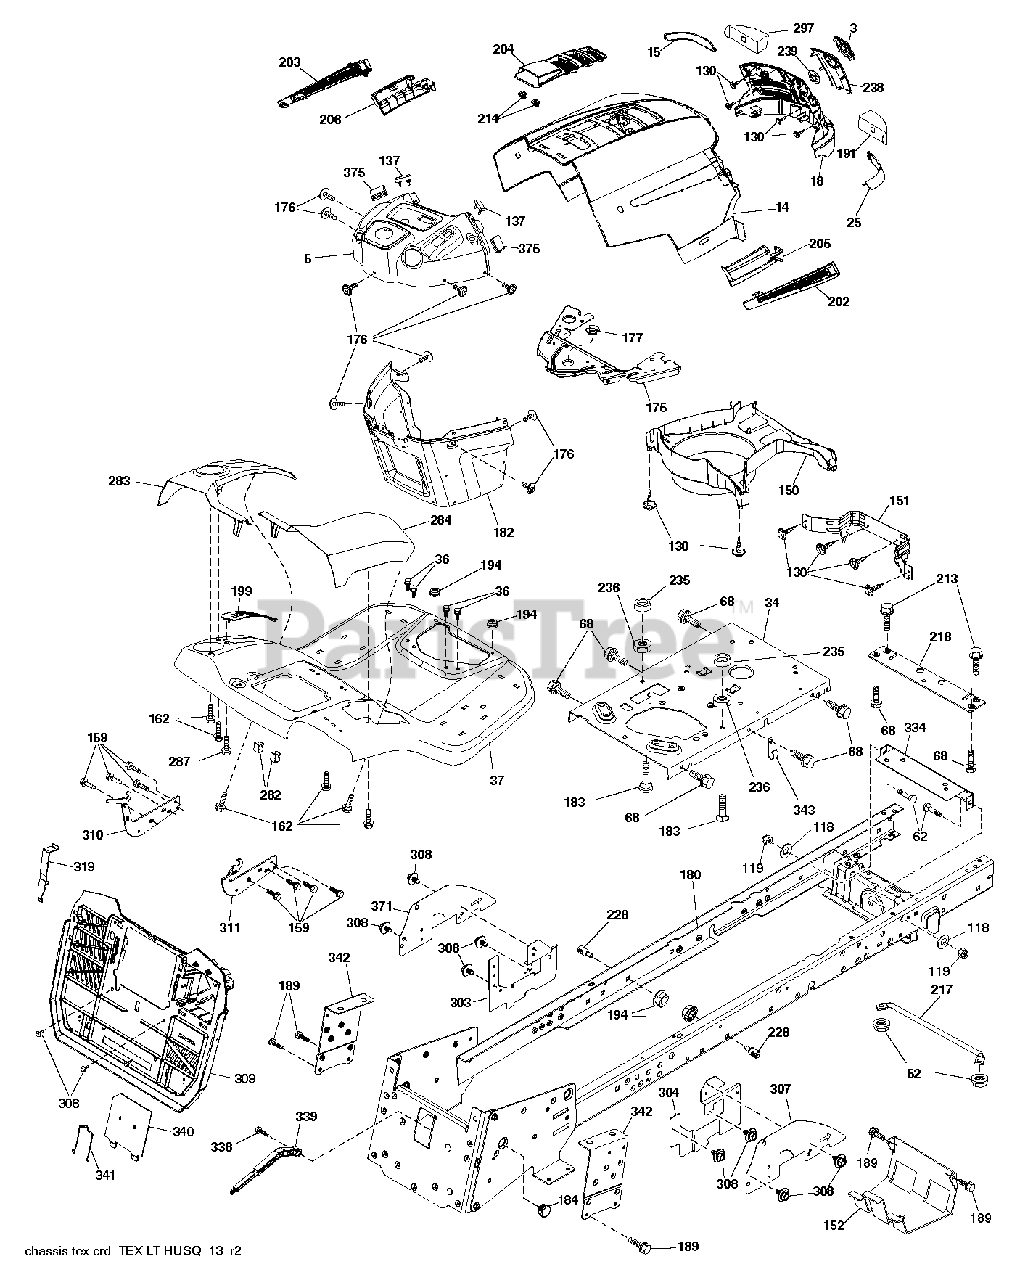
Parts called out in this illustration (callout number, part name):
3	LOGO.HUSQ.GT.LT.CROWN.H
5	DASH.UPPER.HUSQ.LT.MAN.NO-CHK
14	HOOD.HUSQVARNA.LT.ORANGE
15	LENS.HUSQVARNA LT.RH
18	GRILLE.SVC.HUSQVARNA.GREY
25	LENS.HUSQVARNA LT.RH
34	PLATE.ENGINE.10GA.CRD.GENII
36	SCREW 5/16"
37	FENDER.TEX.SRD.CRD.FRN.GUARDS
52	LOCKNUT
62	BOLT D
68	SCREW LT
118	WASHER
130	SCREW.#10 X 0.750.BOS
137	BUMPER DASH
151	BRACKET PIVOT
152	SHIELD.BROWNING.W/TEX
159	SCREW, 3/8-16X3/4
162	SCREW.HI-LO.CONSOLE
175	CROSSMEMBER
176	SCREW.#10-24X5/8.RN.QU
177	BUSHING STEERING
180	CHASSIS WLDT TEX CRD
182	DASH.LOWER.PREDATOR LT
183	BOLT.5/16-18X1-1/4 FULL THD
189	SCREW
191	INSERT.REFLECTIVE.RH.
194	NUT LOCK HEX FLANGE 5/16-18
199	PLATE DECK LIFT
202	VENT.SIDE.HUSQVARNA.LT.RT
203	VENT.SIDE.HUSQVARNA.LT.LFT
204	SUBASM.TOP.VENT.HUSQ.LT
205	SKIRT.SIDE.HUSQVARNA.LT.RT
206	SKIRT.SIDE.HUSQVARNA.LT.LEFT
213	BOLT
214	CLIP.RETAINER.TINNER.
217	ROD.PIVOT.HOOD
218	X-PIECE.HOOD.STOP.NON/
228	STUD.FASTNER.W/ANTI-ROTATE
235	SPACER FENDER
236	NUT.CENTERLOCK.5/16-
238	TRIM.HUSQ LT.668
282	CLIP.RETAINER.CONSOLE.LT.HUSQ
283	CONSL.DECKLIFT.LH.SRD.TEX.CRD
284	CONSL.SHIFT.GEAR.RH.SRD.GREY
287	SCREW 1/4X20
297	INSERT REFLECTIVE
303	SHIELD.LWR.LH.LT.30"CRDSRD.PNT
304	SHIELD.LOWER.RH.CRD.GEN.PNT
307	SHIELD UPPER,RH,FENDERSHIFT,CR
308	BOLT, 5/16-18 X 1 3/4
309	BACKPLATE.TEX.CRD.GEN.1
310	LH.ADJUST.HANGER.BRACKET.ASM
311	RH.ADJUST.HANGER.BRACKET.ASM
319	BRACKET.ACTUATOR.BAGGER.SRD
334	BRACKET.ENGINE
338	BOLT BOLT SHOULDER
339	LEVER LEVER BAGGER
340	DOOR.PNT.BATTERY.TRY.TEX.CRD.
341	LATCH
342	SUPPORT SUPPORT FENDER
343	CLIP CLIP
371	SHIELD.UPPER.CRD.SRD.ISO
375	BUMPER CLIP-ON. DASH 1"
